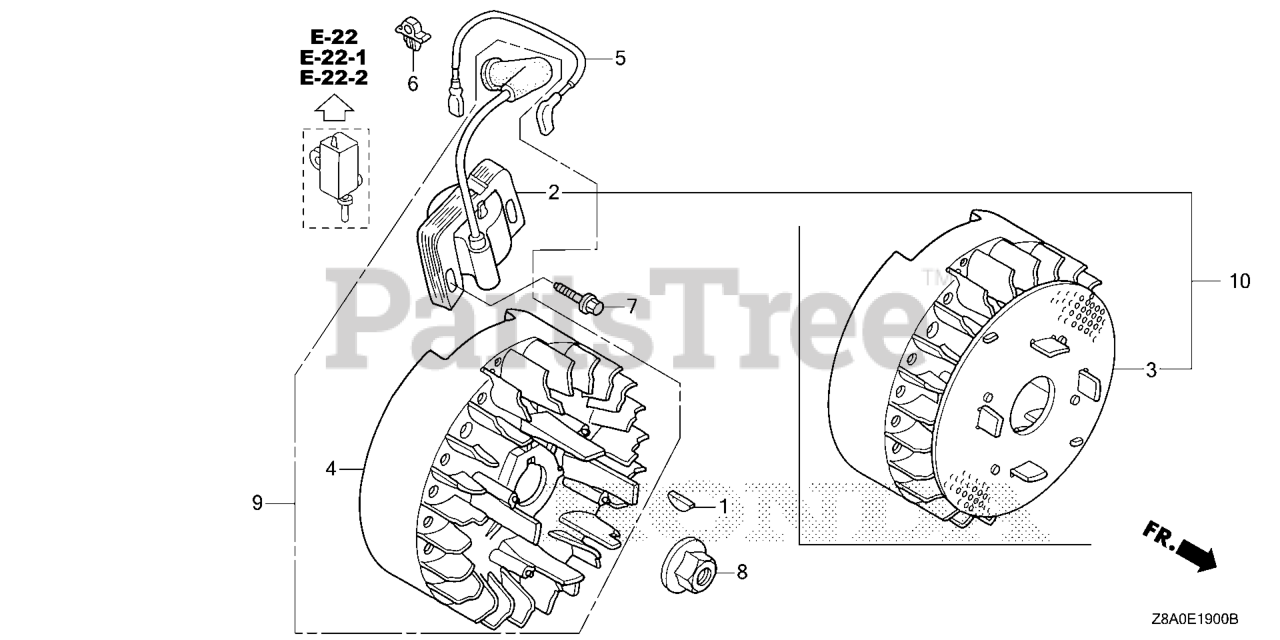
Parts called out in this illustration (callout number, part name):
1	KEY, SPECIAL WOODRUFF (25X18)
2	COIL ASSY., IGNITION (USE FOR F/W OF TEC) (TEC) Use up to Engine SN 3747197.
2	COIL ASSY., IGNITION (PHELON)
4	FLYWHEEL COMP. (TEC) (USE FOR IGN. COIL OF TEC) Use up to Engine SN 3747197.
4	FLYWHEEL COMP. (PHELON) (USE FOR IGN. COIL OF PHELON) (USE FOR PHELON IGNITION COIL)
7	BOLT, FLANGE (6X20) (CT200)
8	NUT, SPECIAL (14MM)
9	FLYWHEEL KIT Use up to Engine SN 3747197.
